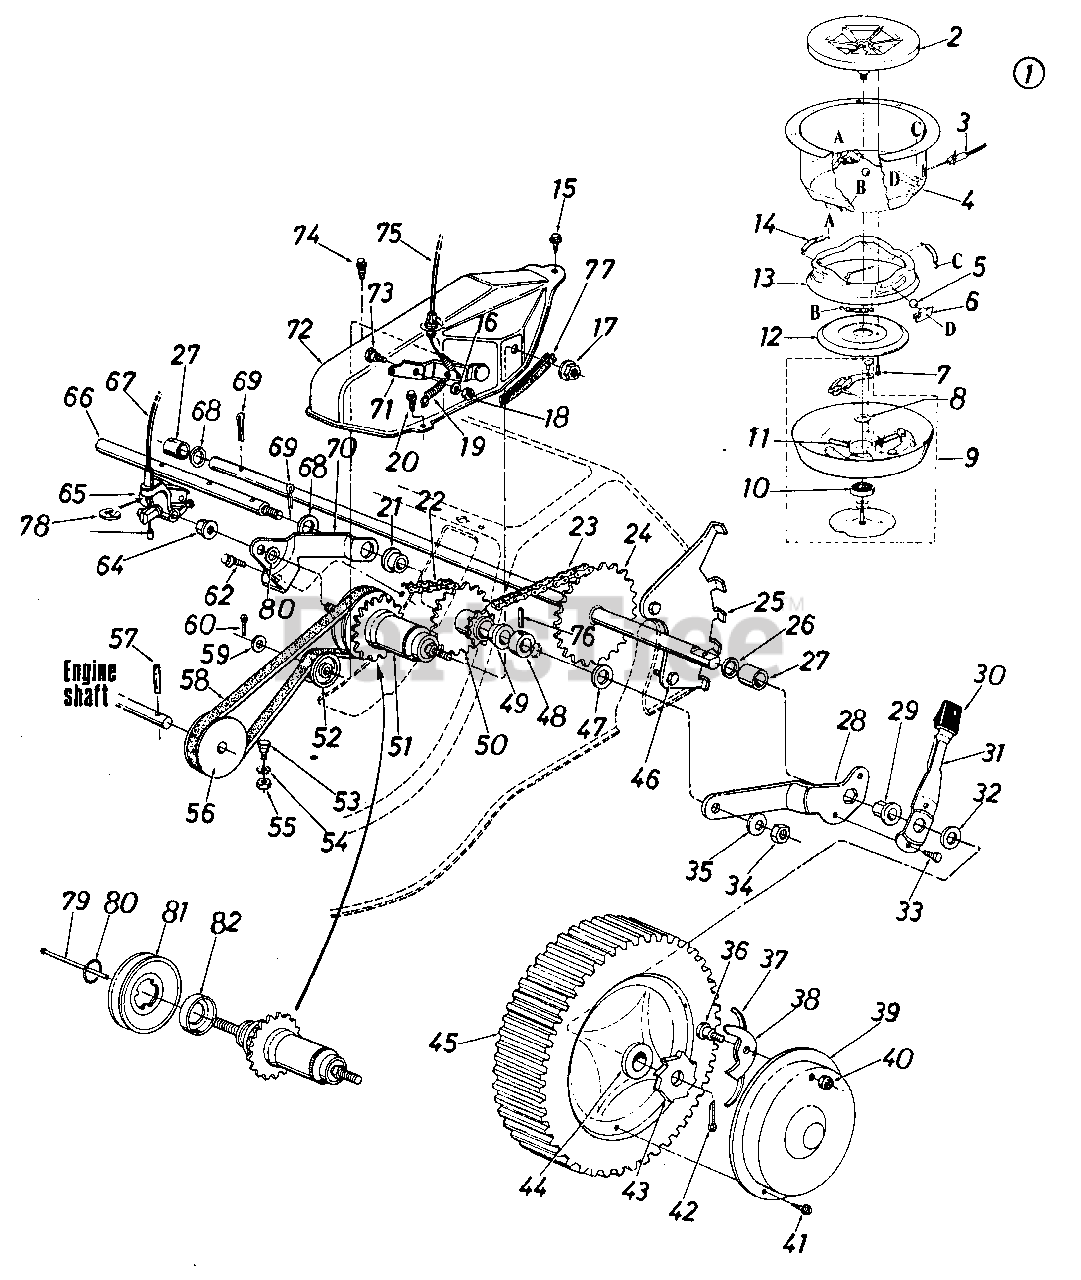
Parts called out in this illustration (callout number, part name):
1	Blade/Brake Clutch Ass'y.
3	BBC-Clutch Cable x 46" Lg.
4	Clutch Housing
5	Steel Ball .500" Dia.
7	Hex Wash. TT-Tap Cl-Scr. 1/4-20 x .75" Lg.
8	Fl-Wash. .690" I.D. x 1.060" O.D.
9	Clutch Blade Housing Ass'y.
10	Ball Brg. .669" I.D. x 1.574 " O.D.
11	Compression Spring .32" O.D x 2.00" Lg.
12	Clutching Cone
13	Brake Cup Cone
14	Extension Spring .35" O.D. x 1.75" Lg.
15	Hex Drilling Scr. #10 x .50" Lg.
16	L-Wash. 1/4" I.D.*
17	Hex Nut 3/8-24 Thd.
18	Hex Nut 1/4-20 Thd.*
19	Extension Spring .33" O.D. x 1.12" Lg.
20	Hex Wash. S-Tap Scr. 1/4-20 x .50" Lg.
21	Flg. Brg. .506" I.D. Plastic
22	#48 Chain 1/2" Pitch x 38 Links (Endless)
23	#48 Chain 1/2" Pitch x 32 Links (Endless)
24	Rear Shaft Ass'y. 20.75" Lg.
25	Index Plate Rear L.H.
26	Fl-Wash. .510" I.D. x 1.0" O.D.
27	Spacer .740" I.D. x .83" O.D.
28	Pivot Brkt. L.H.
29	Hex Flange Brg. .506" 1. D. Plastic
30	Spring Lever Knob
31	Spring Lever
32	Fl-Wash. .531" I.D. x .930" O.D.
33	Hex B-Tap Scr. 1/4 x .38" Lg.
34	Hex Jam Nut 3/8-16 Thd.
35	Bell-Wash. .400" I.D. x .88" O.D.
36	Shld. Bolt .342" Dia. x .268
37	Spring Nylon
38	Pawl
40	Hex Ins. L-Nut 1/4-20 Thd.
41	Pan Hd. Tap Scr. #12 x .50" Lg.*
42	Cotter Pin 1/8" Dia. x 1.00" Lg.*
43	Ratchet Wheel 1.62" O.D.
44	Fl-Ball Brg. 1/2" I.D.
45	Wheel Ass'y. Comp. 8 x 1 .75
46	Hex L-Wash. Hd. AB-Tap Scr. 1/4 x .62" Lg.
47	Bell-Wash. .400" I.D. x 1.13" O.D.
48	Spacer.505" I.D. x .88" O.D.
49	Flg. Brg. .506" I.D. Plastic
50	9 and 21 Tooth Sprocket Ass'y.
51	Shimano 3-Sp. Hub w/ 18 Tooth Sprocket
52	Fl-idler Plastic 1.62" Dia.
53	Shld. Bolt .437" Dia. x .180
54	L-Wash. 5/16" I.D.*
55	Hex Nut 5/16-18 Thd.*
56	1/2" "V"-Engine Pulley .50" I.D. x 2.80" O.D.
57	Spring Pin Spir. 3/16" Dia. x 1.50" Lg.
58	"V"-Belt 1/2" x 26.0" Lg.
59	Fl-Wash. .531" I.D. x .930" O.D.
60	Cotter Pin 1/8" Dia. x 1.00" Lg.*
62	Hex Wash. Hd. Tap Scr. 5/16-18 x .75" Lg.
64	Hex Nut 3/8-24 Thd.
65	Shimano 3-Sp. Shift Bell Crank
66	Pulley Shaft 10" Lg.
67	Sh imano 3-Sp. Solid Shift Cable
68	Fl-Wash. .531" I.D. x .930" O.D.
69	Cotter Pin 3/32" Dia. x 1.00" Lg.*
70	3-Sp. Hub Bracket
71	Idler Bracket Ass'y.
72	3-Sp. Belt Cover
73	Shld. Bolt .375" Dia. x .181
74	Hex TT-Tap Scr. 1/4-20 x .75" Lg.
75	S.P. Cable 53" Lg. Blue
76	Spring Pin Spir. 3/16" Dia. x 1.0" Lg.
78	Snap Ring
79	Shifting Pin
80	Pulley Snap Ring
81	1/2" V-Pulley 1.375" I.D. x 3.25" O.D.
82	Shimano 3-Sp. Dust Cover
